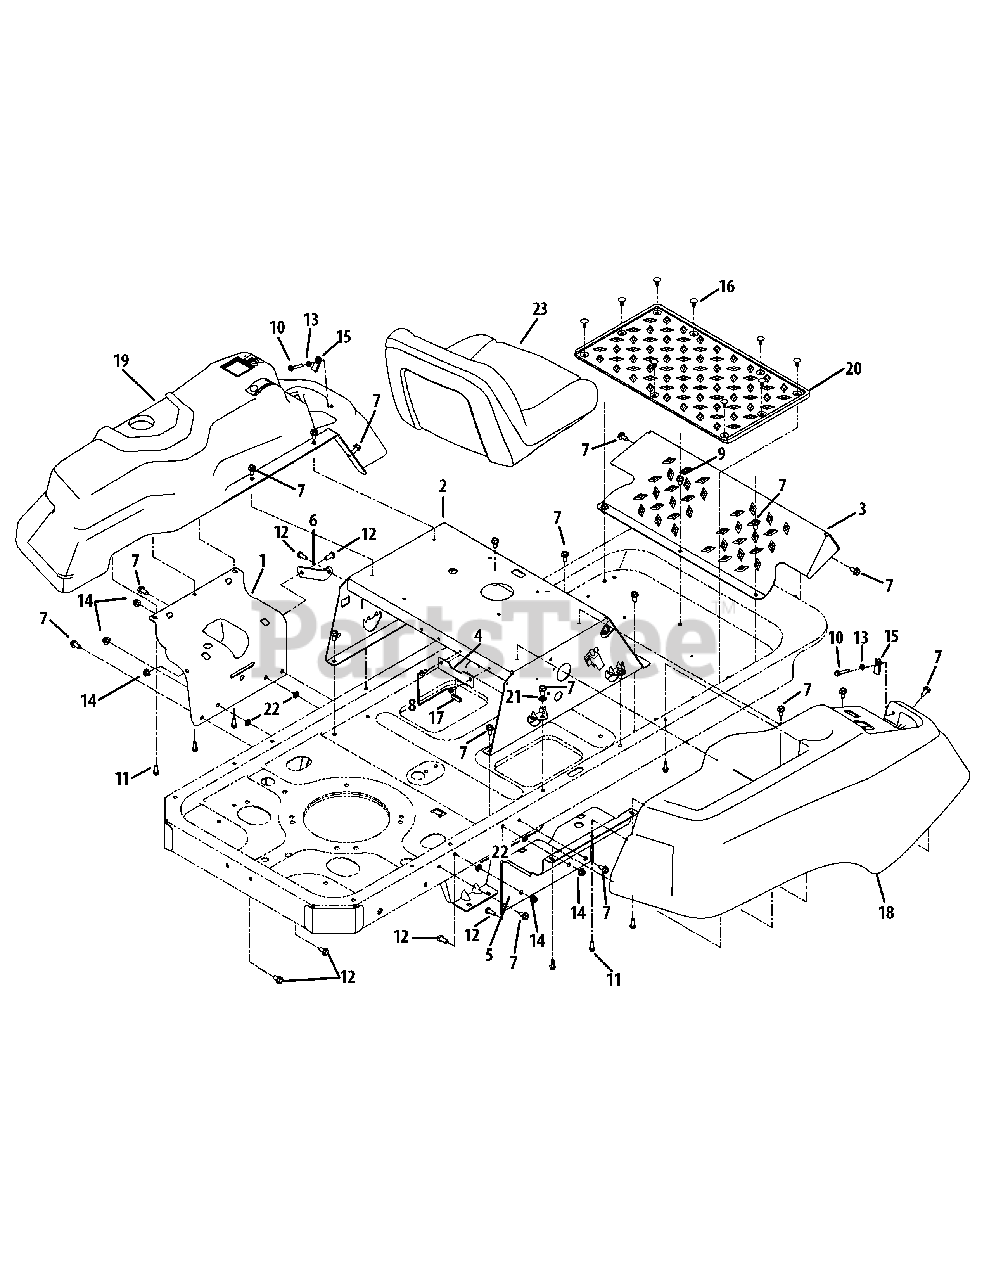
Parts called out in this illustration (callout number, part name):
7	Hex Washer Screw 5/16-18 x .75
8	Hex Wash S-Tapp Screw 1/4-20 x .50
9	Self-tapping Screw 5/16-18 x .625
10	Hex Wash HD Bolt 1/4-20 x 1.50" Lg.
11	Hex Tapp Screw 1/4 x .75" Lg.
12	Hex Screw 5/16-18 x .75
13	Hex Jam Nut 1/4-20
14	Hex L-Flg.Nut 5/16-18 Gr. F, Nylon
15	U-Type Speed Nut 1/4-20
16	Ratchet Clip
17	Trim Strip
18	Console, RH
19	Console, LH
20	Foot Pat
21	Ext. Tooth Washer, 3/8
22	Push Speed Nut
23	High Back Seat
23	Seat (Columbia)
